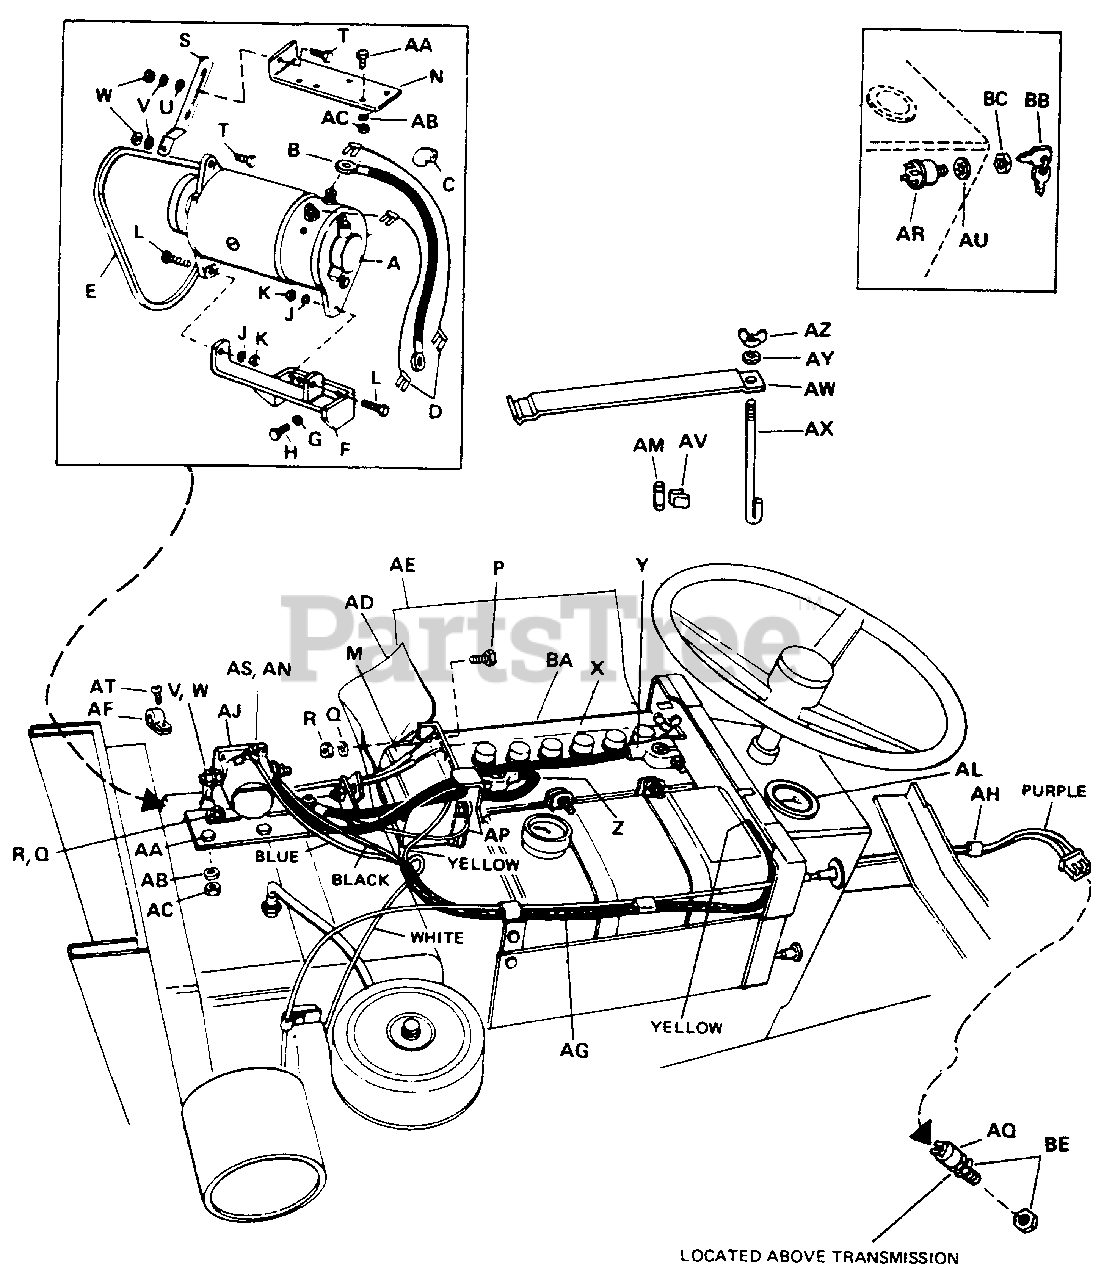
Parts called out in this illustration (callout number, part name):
A	Motor-Generator
B	Generator Start Cable
C	Terminal Cover
D	Reg. Gen. Wire
F	Support Assembly
G	Lock Washer, 5/16"
H	Hex. Capscrew, 5/16 18 x 3/4" lg.
J	Lock Washer, 5/16"
K	Full Hex. Nut, 5/16"-18
L	Hex. Capscrew, 5/16"-18 x 1-1/4"
M	Voltage Regulator
P	Hex. Capscrew, 1/4-20 x 3/4" lg.
Q	Lock Washer, 1/4"
R	Full Hex. Nut, 1/4"-20
S	Belt Tightener
T	Hex. Capscrew, 5/16-18 x 3/4" lg.
U	Plain Washer, 5/16"
V	Lock Washer, 5/16"
W	Full Hex.Nut, 5/16"-18
Y	Cable (Battery to Solenoid)
Z	Cable (Battery to Ground)
AA	Hex Capscrew, 1/4-20 x 1/2" lg
AB	Lock Washer, 1/4"
AC	Full Hex.Nut, 1/4"-20
AD	Battery Insulation
AE	Fuel Tank Insulation
AF	Wire Clamp (Generator Cable)
AG	Harness Assembly
AH	Speed Clip
AK	Full Hex. Nut, 1/4"-20
AL	Ammeter
AM	Fuse, 20 AMP
AN	Full Hex. Nut, 10-32
AP	Wire (Ground to Ground)
AQ	Safety Switch
AR	Starter Switch w/Keys
AS	Lock Washer, ext. No. 10
AT	Rd.Hd.Screw 10-24 x 1/2"
AU	Lock Washer Int. 9/16"
AV	Clip Fuse
AW	Battery Bracket
AY	Lock Washer, 1/4"
BA	Film (SIMPLICITY)
BC	Hex Nut-Special
BE	Nut
